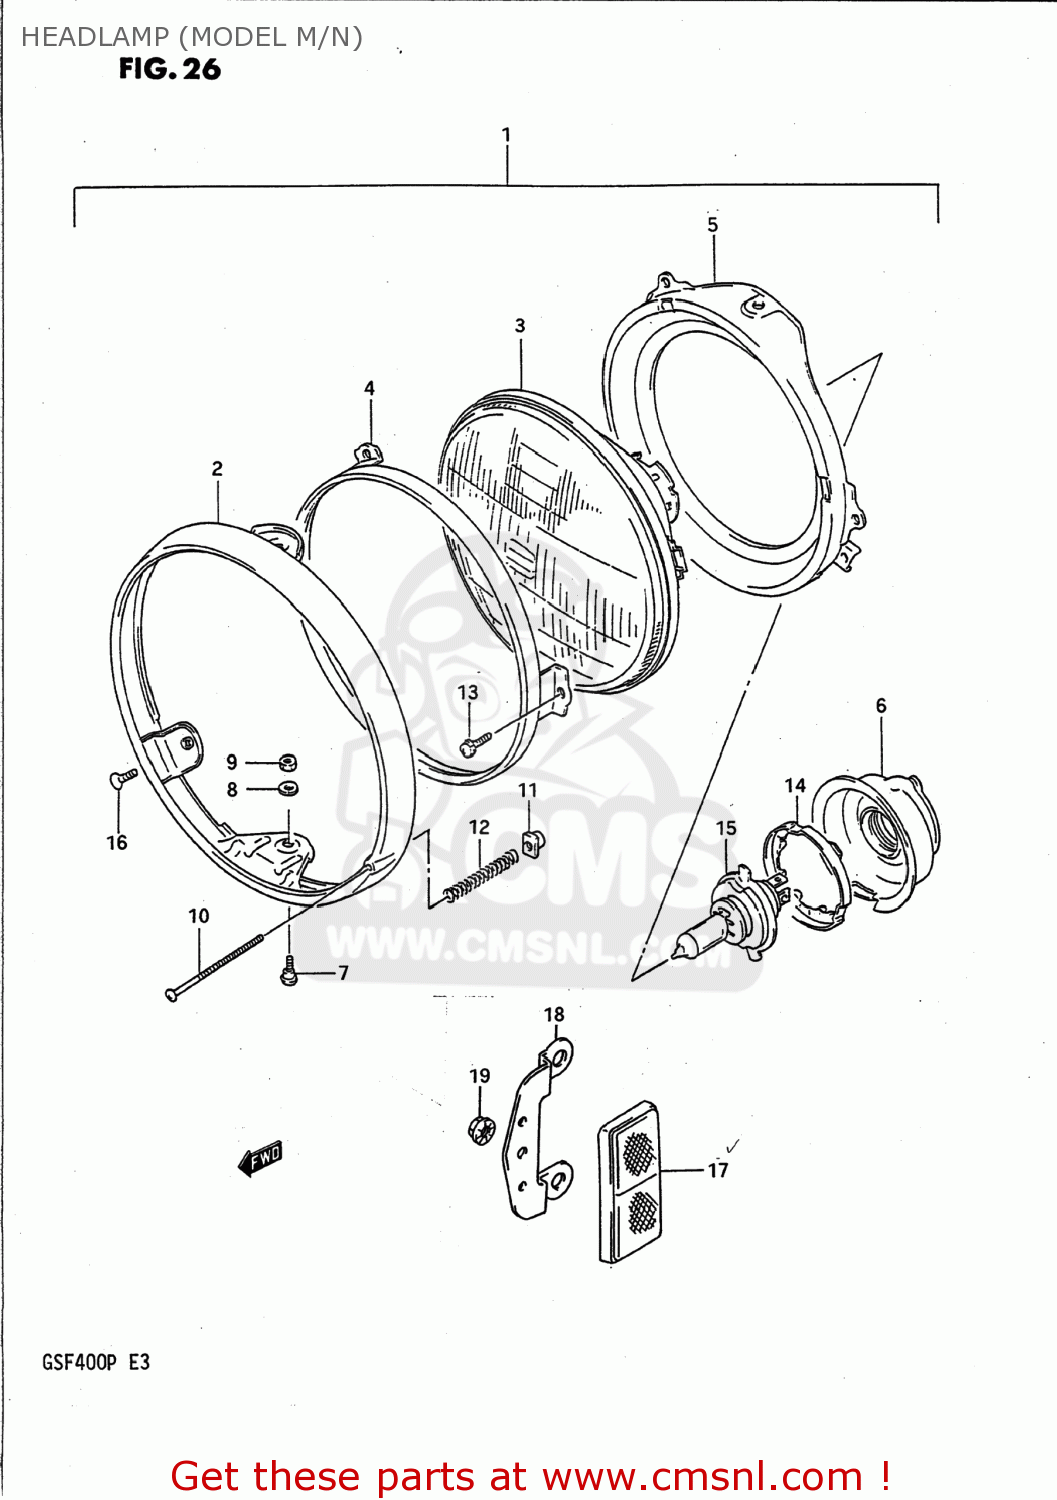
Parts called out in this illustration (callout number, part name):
1	HEADLAMP ASSY
2	RIM,HEADLAMP
3	LAMP UNIT
4	RETAINING RING
5	RING
6	COVER,HEADLAMP SOCKET
7	H/LAMP LENS UNIT FITING SCRE
8	LOCK WASHER
9	NUT
10	SCREW,HEADLAMP ADJUST
11	NUT
12	SPRING,ADJUSTING
13	SCREWM4X0.7X10
14	SETTING,BULB
15	BULB(12V60/55W,H4)
16	SCREW 5X12
17	REFLEX REFLECTOR,FR SIDE
18	BRACKET,FRONT SIDE REFLECTOR
19	NUT
